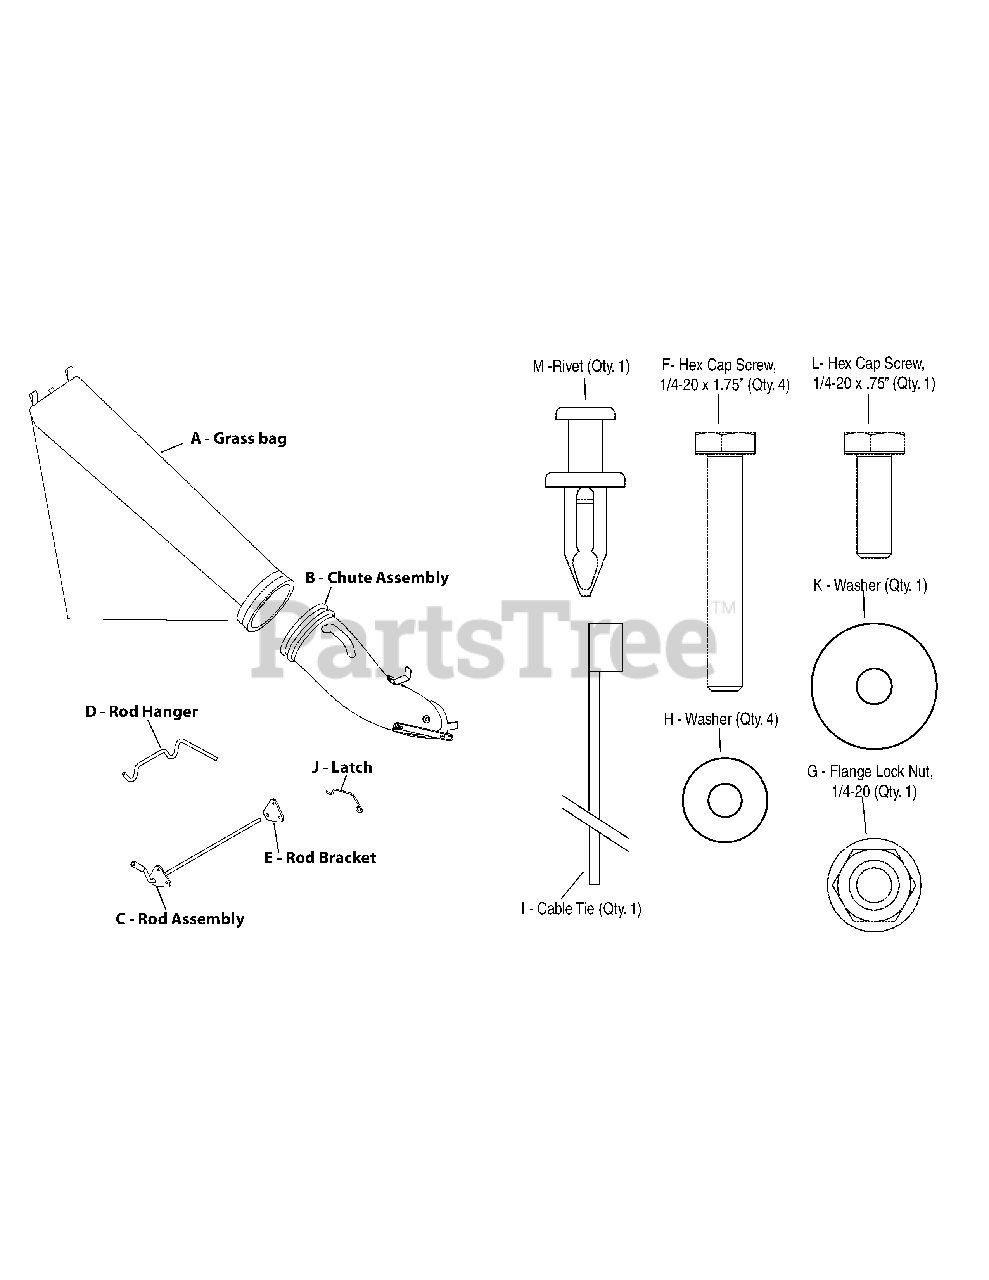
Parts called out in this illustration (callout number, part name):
B	Chute Assembly
D	Rod Hanger
F	Hex Cap Screw,1/4-20 x 1.75" (Qty. 4)
G	Flange Lock Nut,1/4-20 (Qty. 1)
H	Washer (Qty. 4)
I	Cable Tie (Qty. 1)
K	Washer (Qty. 1)
L	Hex Cap Screw,1/4-20 x .75" (Qty. 1)
M	Rivet (Qty. 1)
